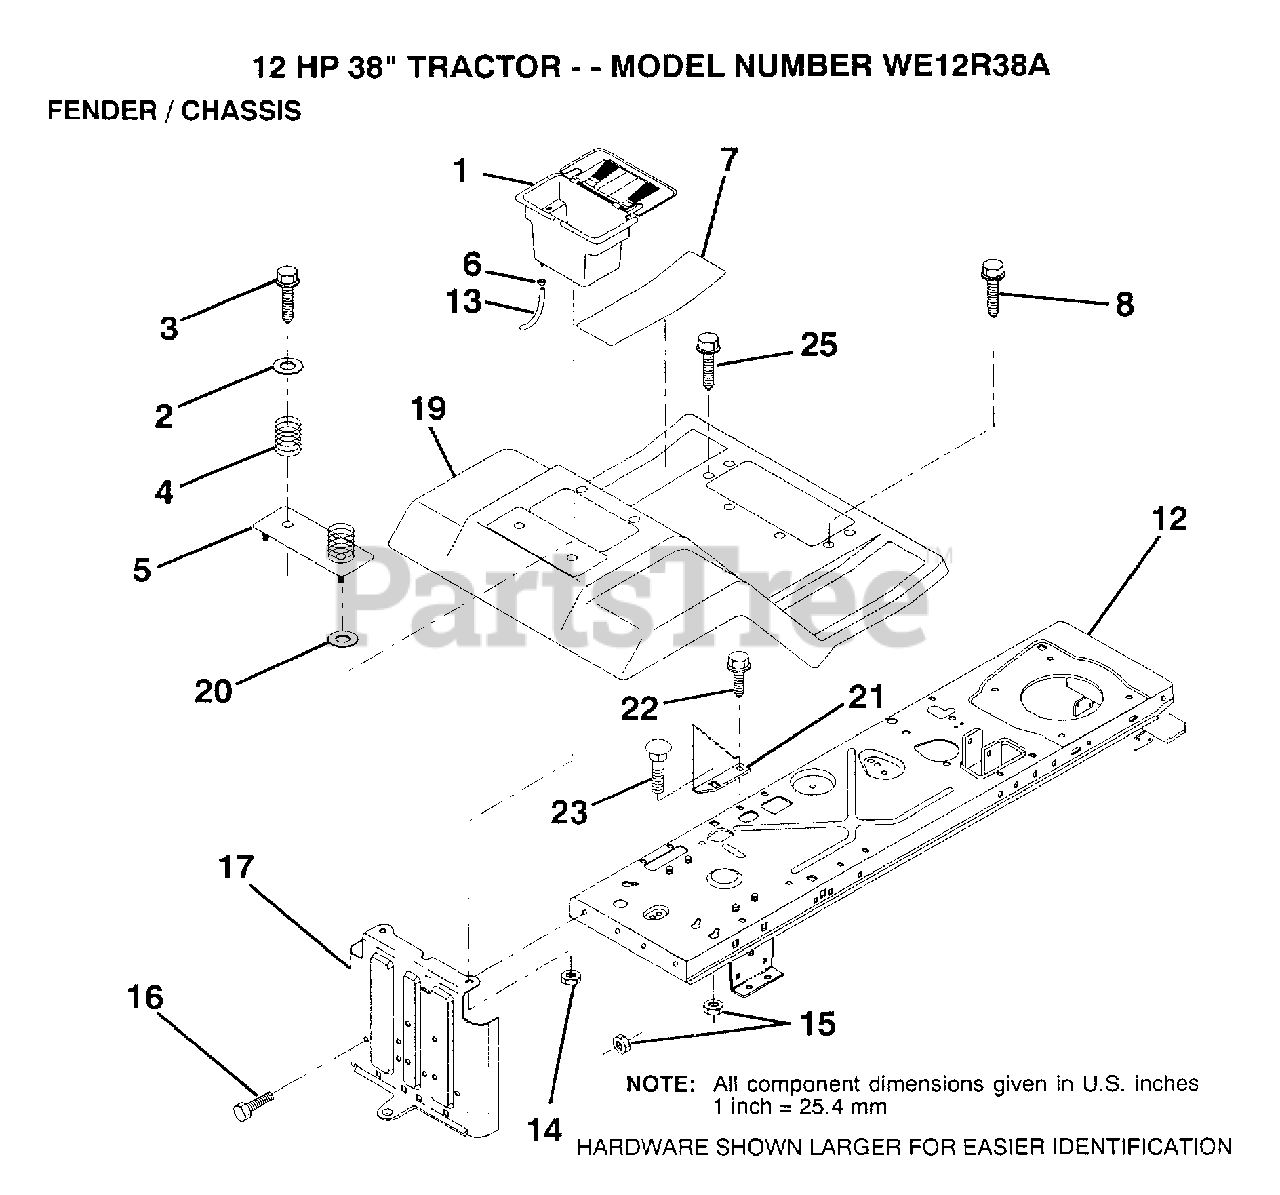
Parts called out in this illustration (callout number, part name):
2	WASHER
3	SCREW
4	SPRING COMPRESSIO
5	"PLATE, BATTERY"
6	HOSE CLAMP T
7	PAD FOOTREST
8	SCREW
13	TUBE T
14	NUT
16	BOLT
17	DRAWBAR
22	SCREW LT
25	SCREW TI
